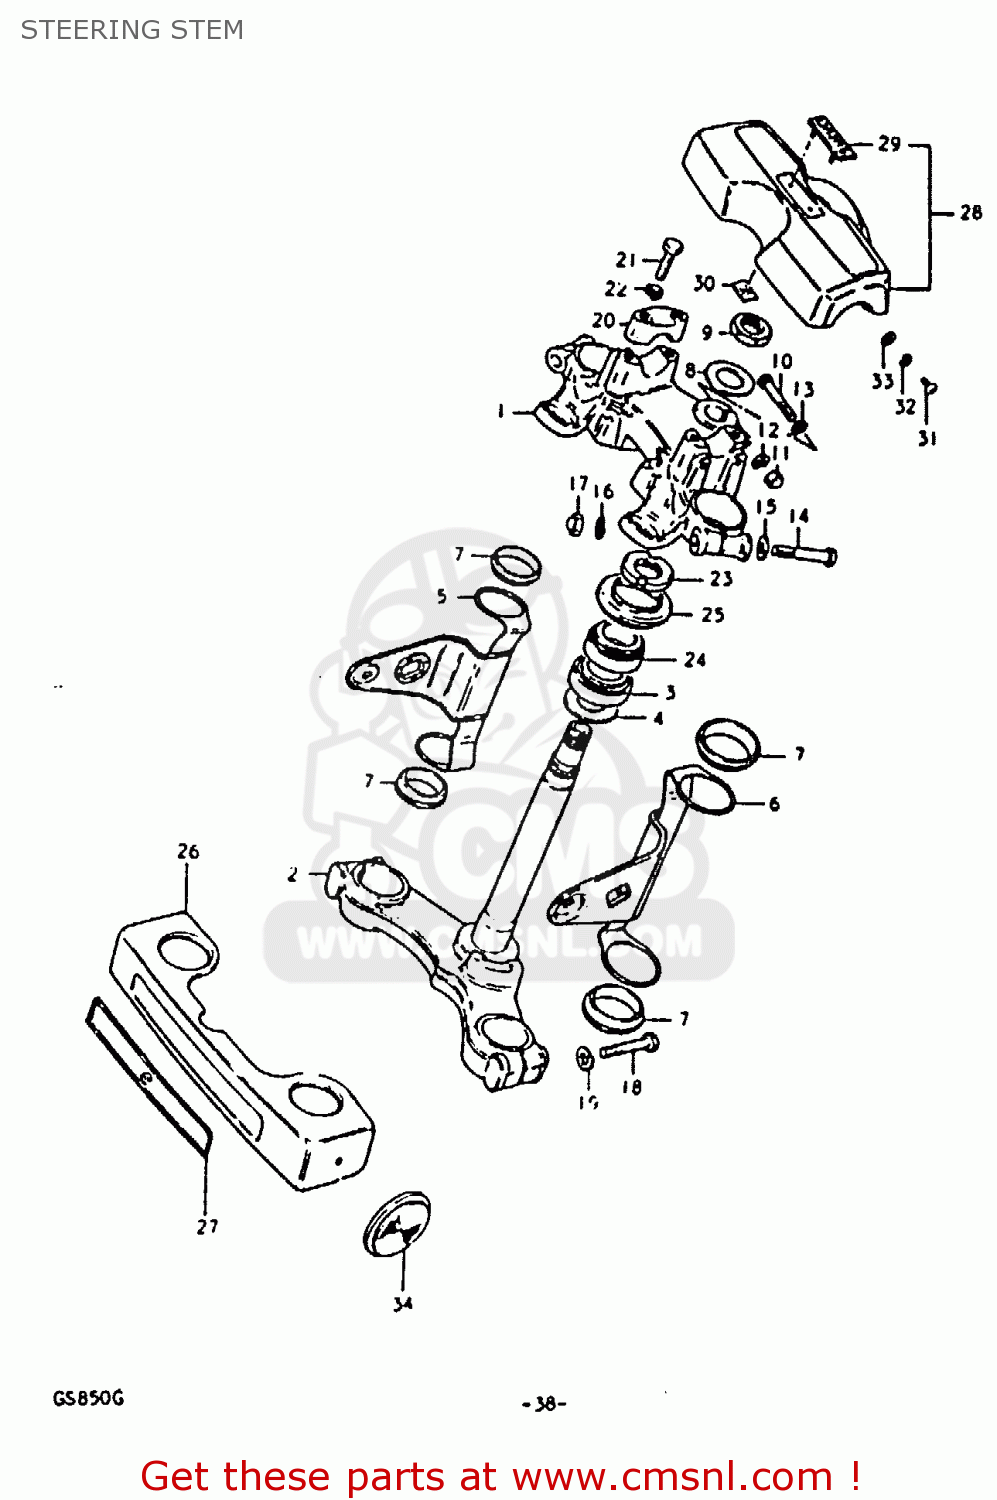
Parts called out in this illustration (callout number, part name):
1	HEAD,STEERING STEM
2	STEM,STEERING
3	BEARING
4	WASHER,THRUST
5	BRACKET,HEADLAMP,RIGHT
6	BRACKET,HEADLAMP,LEFT
7	CUSHION,HEADLAMP BRACKET
8	WASHER
9	NUT,FR FORK UPR BRACKET
10	BOLT 8X50
11	NUT
12	LOCK WASHER
13	WASHER
14	BOLT 10X55
15	WASHER
16	LOCK WASHER
17	NUT, LOWER LH
18	BOLT
19	LOCK WASHER
20	HOLDER,HANDLE(BLACK)
21	BOLT
22	LOCK WASHER
23	NUT,STEERING STEM(25X44X10)
24	TAPER,ROLLER BEARING
25	DUST SEAL,STEERING,UPPER
26	COVER,FRONT FORK
27	EMBLEM
28	PAD,HANDLEBAR
29	EMBLEM,HANDLE COVER PAD
30	NUT
31	SCREW
32	LOCK WASHER
33	WASHER
34	REFLEX REFLECTOR,RR
